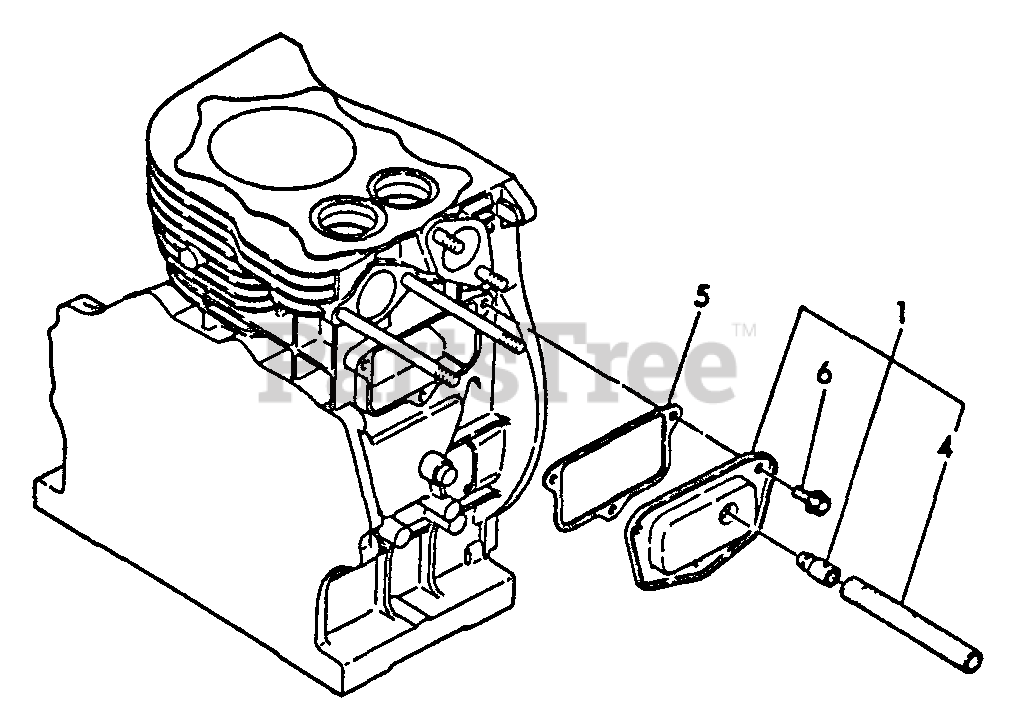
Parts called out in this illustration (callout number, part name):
1	BREATHER ASSY
4	PIPE, BREATHER
6	BOLT - 6×8 -- PLATED
